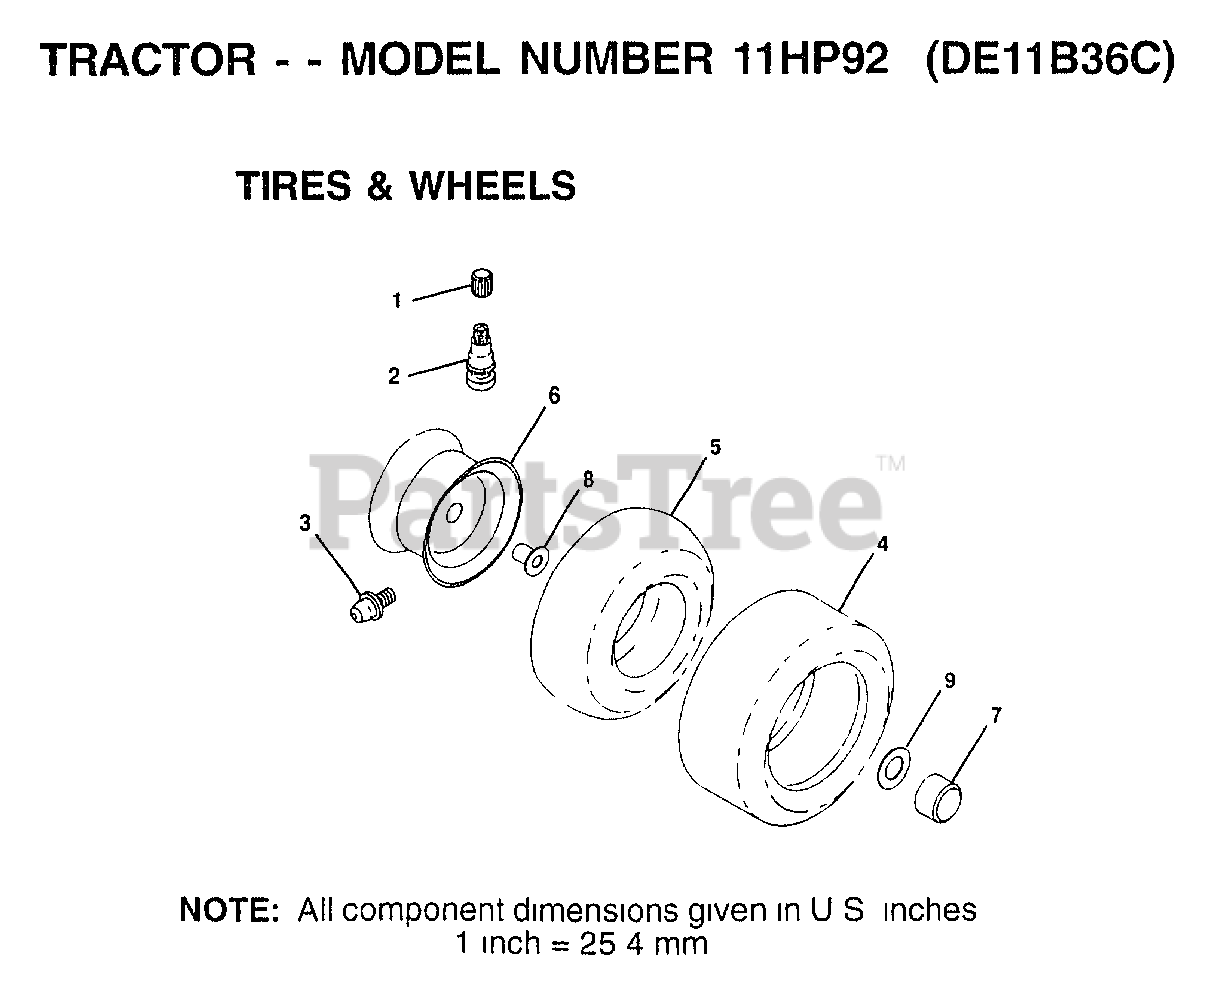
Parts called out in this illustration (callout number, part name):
1	VALVE CAP
2	VALVE STEM LT
3	FITTING LT
5	TUBE.5.3/4.5/6
5	TUBE.16X6.5/7.5-8
6	"RIM.FRT.6"".ASM"
6	"RIM REAR 8"""
7	HUB CAP
8	"FLANGE, BEARING"
9	WASHER
